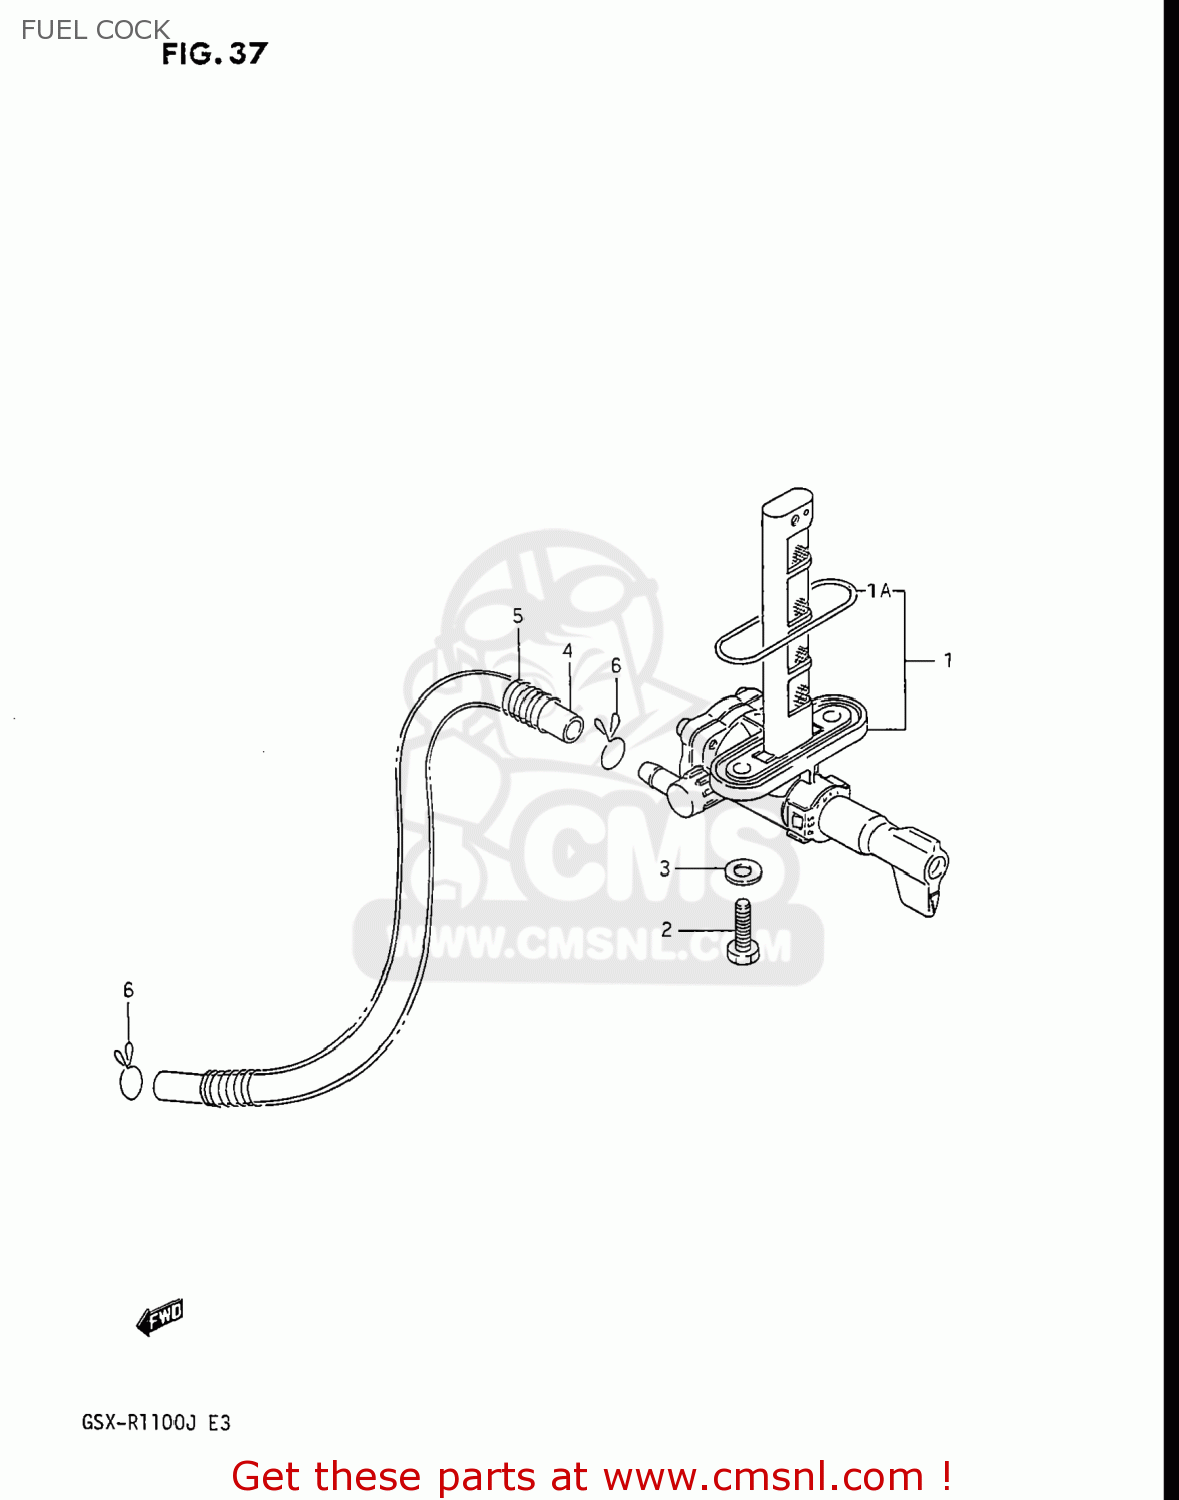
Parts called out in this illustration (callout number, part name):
1	COCK ASSY,FUEL
1A	O RING
2	BOLT(6X20)
3	GASKET
4	HOSE
5	SPRING
6	CLIP
